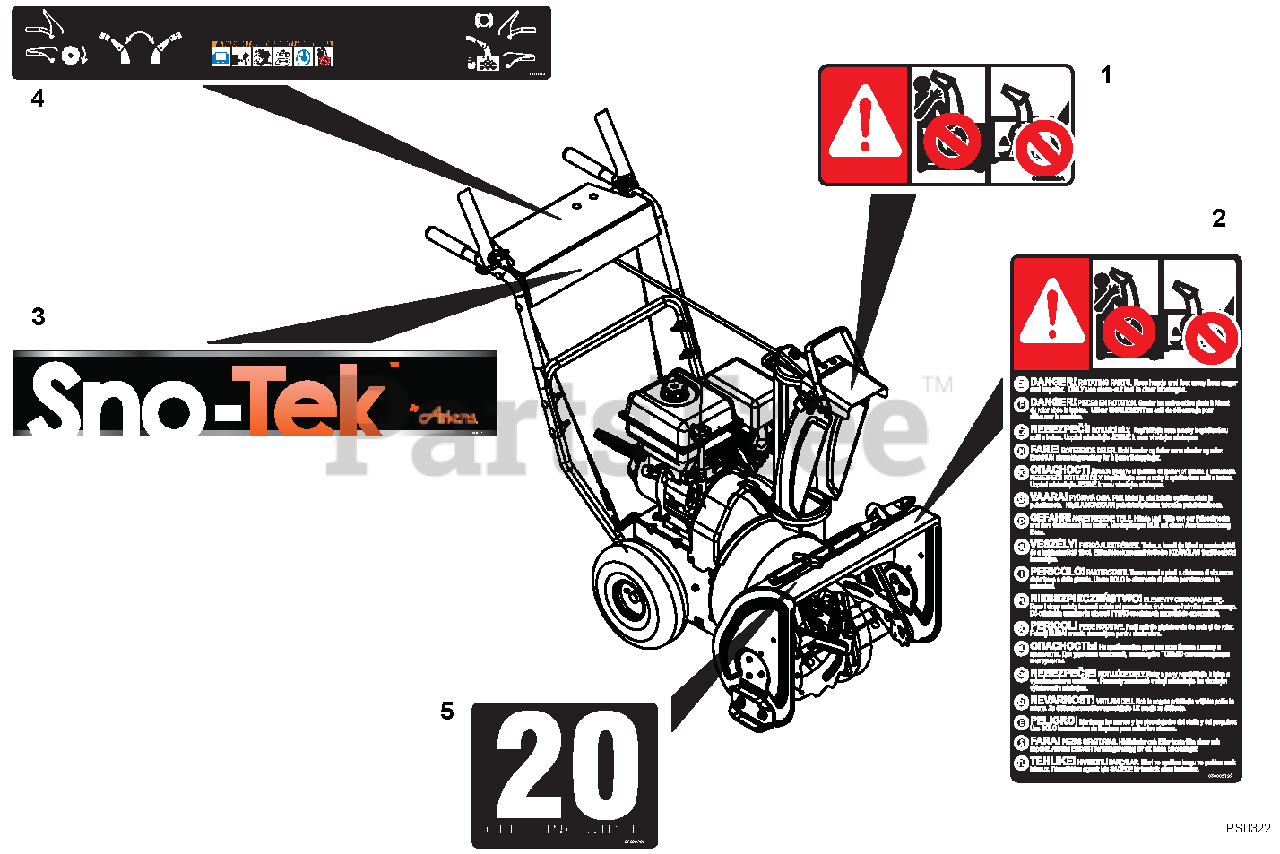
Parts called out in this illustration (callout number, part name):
1	DECAL, DANGER
2	DECAL, DANGER
3	DECAL, DASH - SNO-TEK
4	DECAL, CTRL PANEL, SINGLE SPD
5	DECAL, HOUSING SNO-TEK 20
